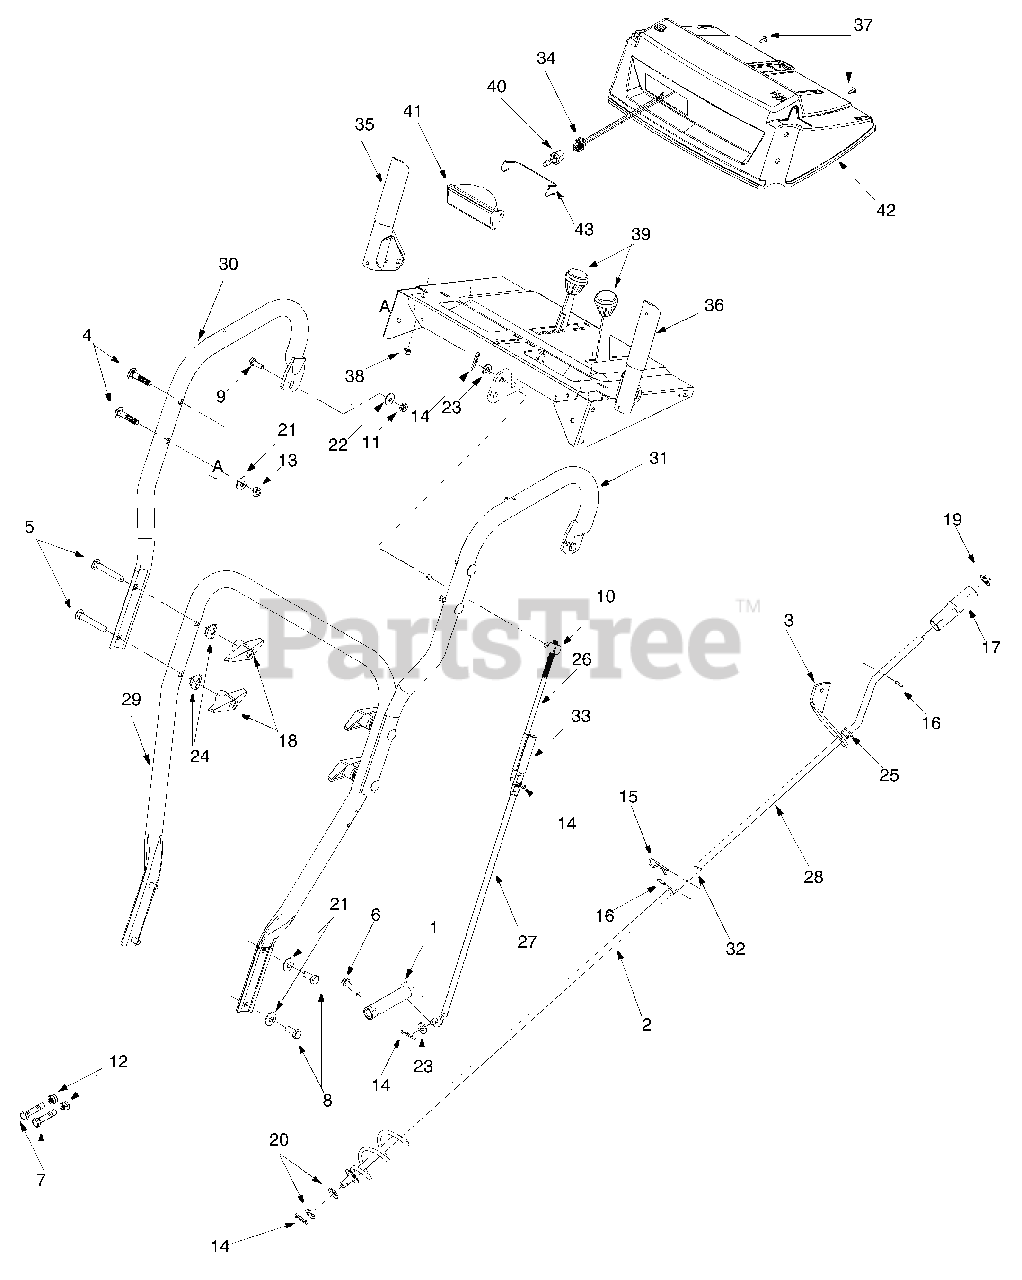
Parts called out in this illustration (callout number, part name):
4	Carr. Bolt 5/16-18 x 1.5
5	Carr. Screw 5/16-18 x 2.25 Gr.5
6	Hex Washer Head TT Screw 1/4-20 x 1.0
7	Shear Bolt 5/16-18 x 1.5
8	Hex Bolt 5/16-18 x 0.75 Gr.5
9	Hex Bolt 1/4-20 x 0.75 Gr.5
10	Ferrule
11	Hex Nut: 1/4-20
12	Hex Lock Nut
13	Hex Nut: 5/16-18
14	Cotter Pin
15	Click Pin
16	Roll Pin
17	Chute Crank Knob
20	Flat Washer
21	Belleville Washer
22	Bell Washer
23	Flat Washer
24	Saddle Washer
25	Plastic Bushing
26	Shift Rod: Upper
27	Shift Rod: Lower
30	Handle: C Style RH
33	Clutch Rod Connector
34	Harness, Halogen Light
35	Handle Engagement Assembly: RH Black
36	Handle Engagement Assembly: LH Black
37	Hex Washer Hd. Sp. Screw
38	Hex Sems Nut
39	Shift Knob
40	Halogen Lamp
41	Lamp Housing
42	Handle Panel: Yellow w/ Tilt, Light
43	Halogen Retainer: Handle
